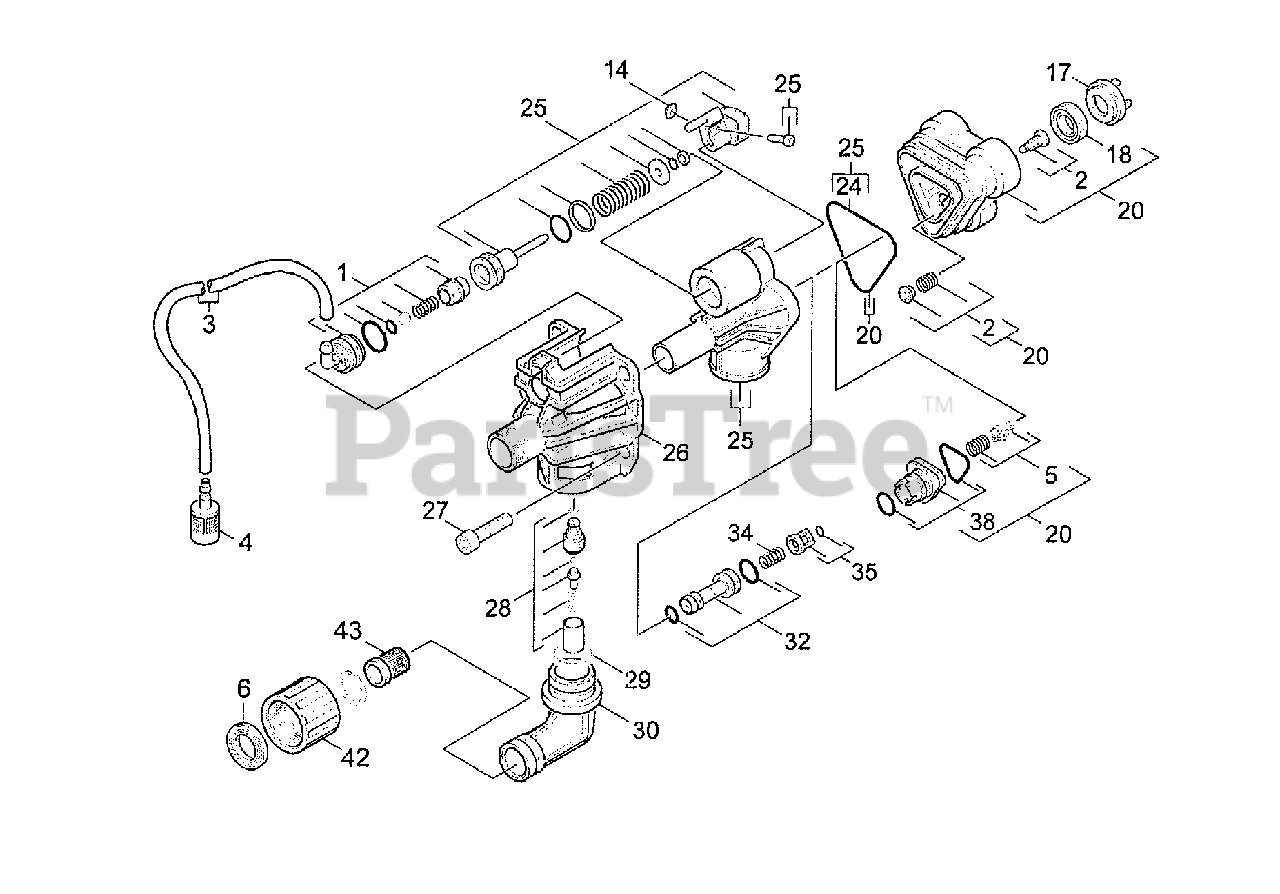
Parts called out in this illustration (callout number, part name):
1	Anti-Siphon Valve
2	Spring & Seat
17	Support Disc
18	Grooved Ring
20	Cylinder Set
25	Rebuild Kit
30	Ellbow, Inlet
